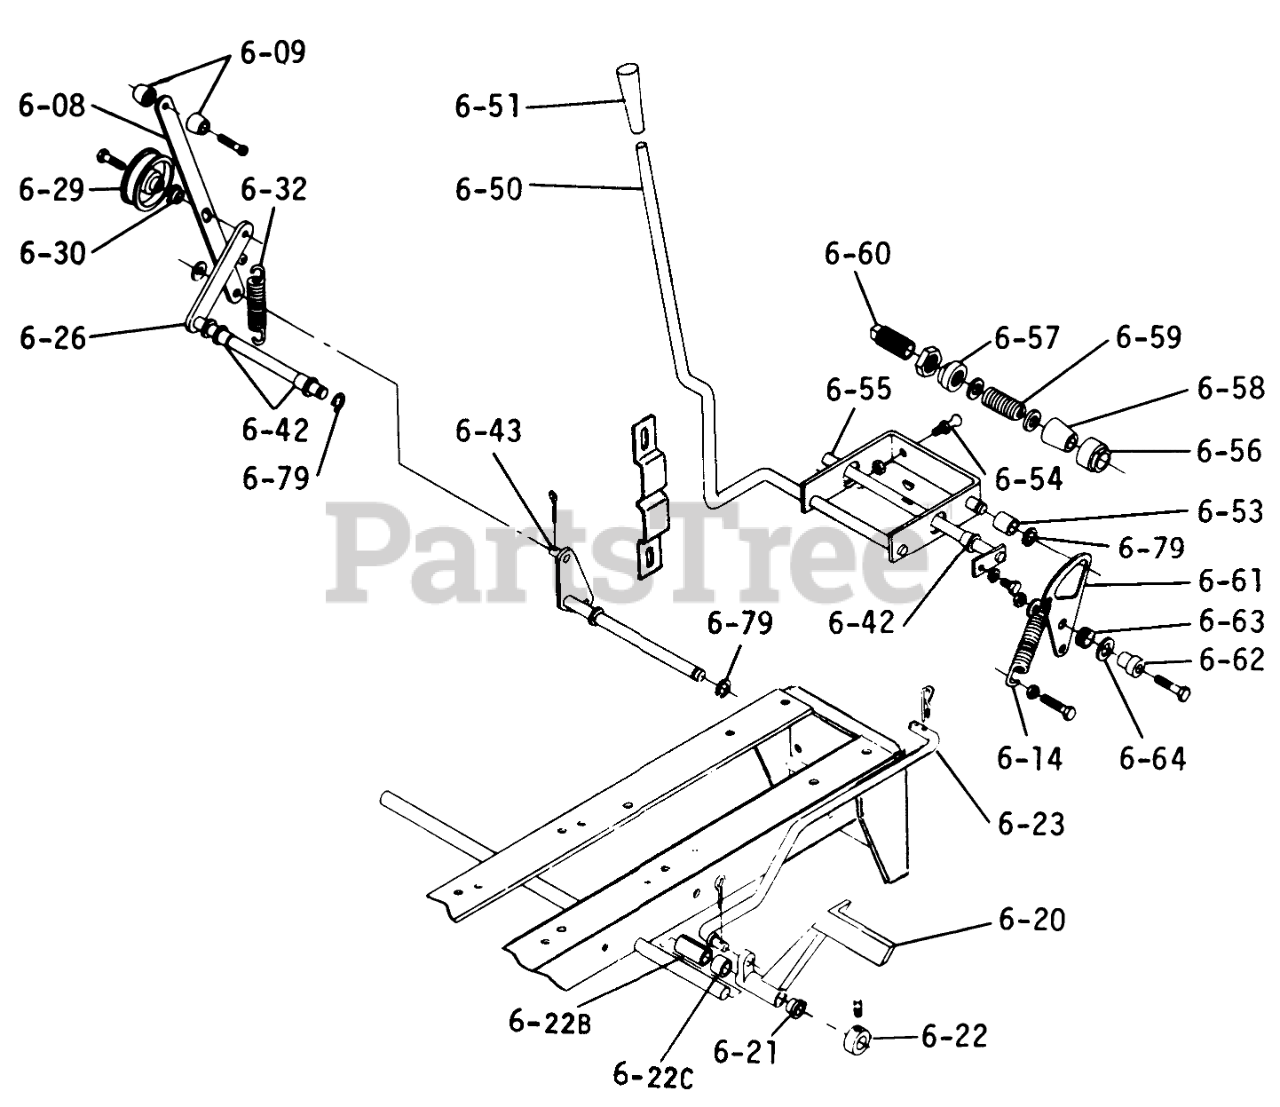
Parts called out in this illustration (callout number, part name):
6-08	HANDLE R (NS)
6-09	KNOB
6-09	Machine Screw
6-14	Spring
6-14	Bolt
6-14	Nut
6-20	PEDAL R
6-21	BUSHING
6-22	Collar
6-22	SCREW-SET
6-22B	SPACER
6-22C	Spacer
6-23	Gasket
6-26	Idler Arm
6-26	Washer
6-26	Bolt
6-26	Nut
6-29	Idler Pulley
6-29	HEX HD CAP SCREW
6-30	SPACER-BRAKE LINK
6-32	SPRING-EXTENSION
6-42	BUSHING-FLANGED
6-43	ever Brake
6-43	Washer
6-43	Cotter Pin
6-43	E Ring
6-50	Cam Control
6-51	KNOB
6-51	SPRING-DETENT
6-51	WASHER 5/16 SAE
6-51	SCREW
6-53	BEARING-CAM RETURN
6-53	E Ring
6-54	PIN
6-54	Nut
6-55	Cam Pivot Rod
6-55	WOODRUFF KEY
6-55	SCREW
6-56	FRICTION COLLAR
6-57	COLLAR BRKT PIVOT
6-58	FRICTION CONE
6-59	SPRING FRICTION
6-59	Washer
6-59	BUSHING-FLANGED
6-60	Collar Friction
6-61	Cam Plate
6-62	Spacer
6-63	NYLINER BUSHING
6-64	SHIM-WASHER
6-64	Bolt
6-64	Nut
6-64	Washer
6-79	E Ring
